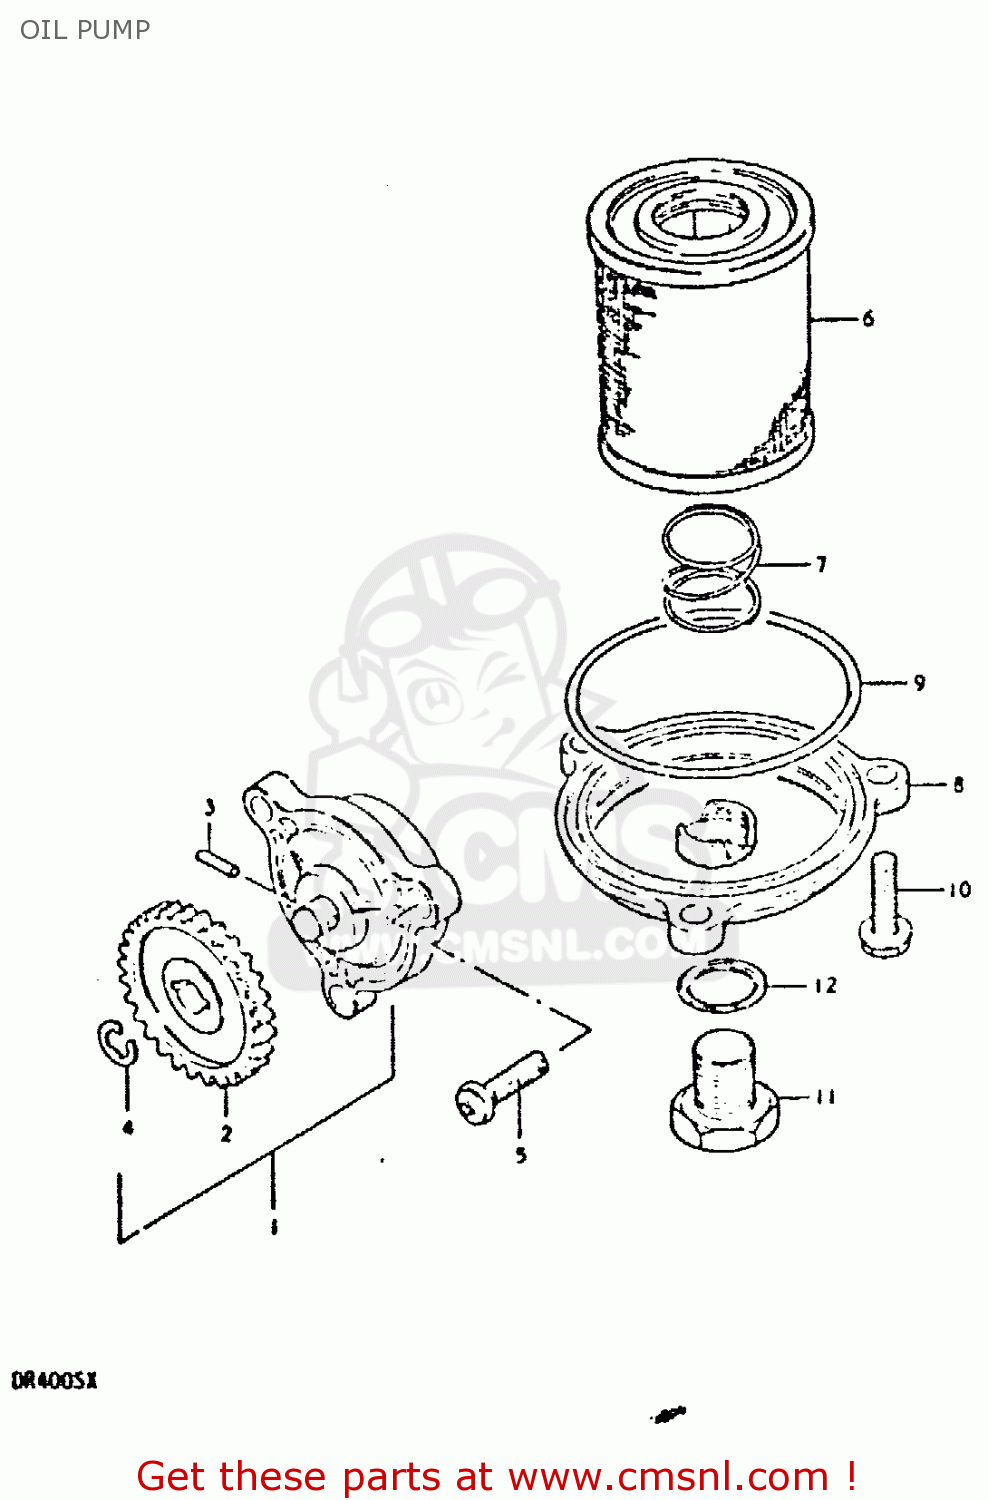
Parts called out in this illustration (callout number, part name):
1	PUMP ASSEMBLY,ENGINE OIL
2	GEAR,OIL PUMP DRIVEN
3	PIN(2.5X11.8)
4	E RING 6MM
5	SCREW
6	STRAINER,OIL
7	SPRING
8	CAP,ENGINE OIL STRAINER
9	O RING(D:2.4,ID:62.6)
10	BOLT,REAR
11	PLUG
12	GASKET(14X19.2X2) (NAS)
